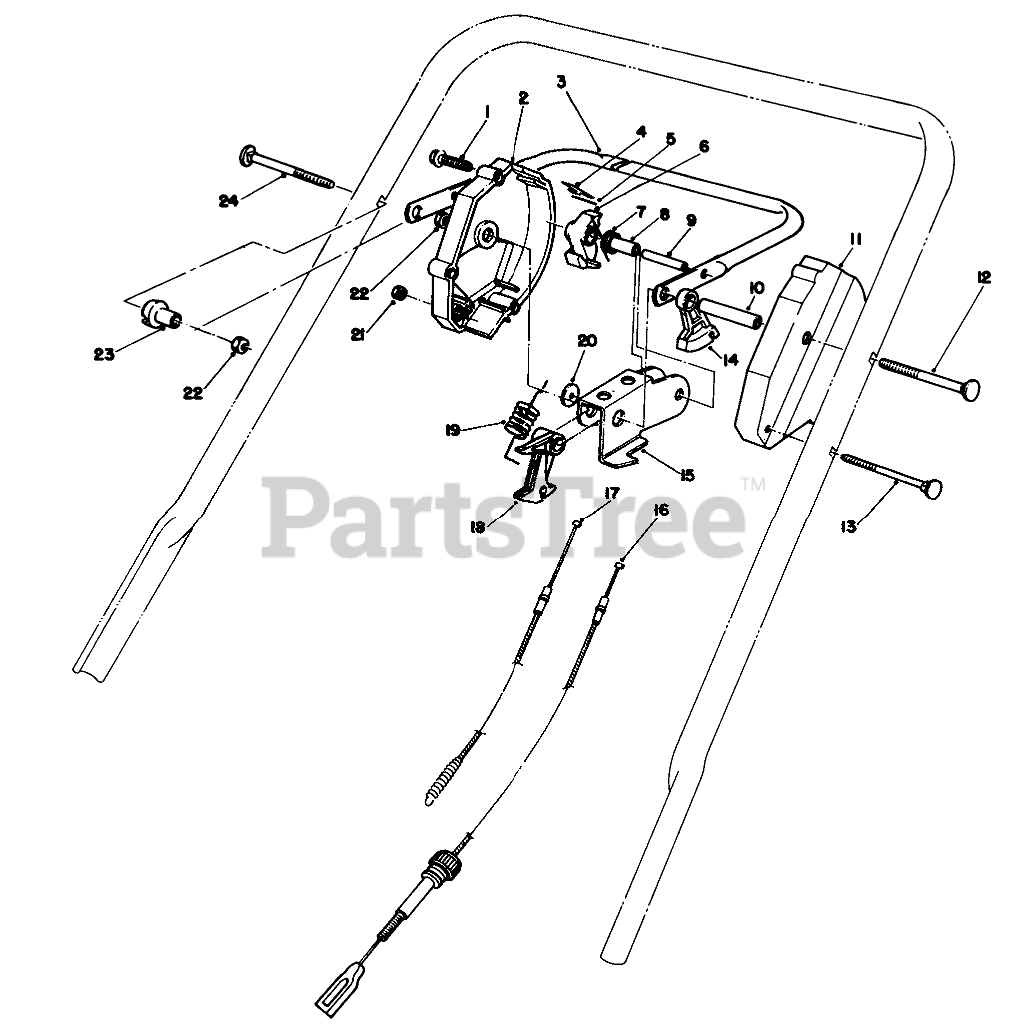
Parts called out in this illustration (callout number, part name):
1	SCREW-HWHTF
2	Housing-Control R.H. (Incl. Ref. #4 & 5)
3	Bar-Control
4	SPRING-LEAF
5	PIN-INSERT
6	HOOK-CONTROL
7	SPRING-TORSION
8	SPACER
9	PIN-ROLL, SLOTTED
10	TUBING-SPACER
11	HOUSING-CONTROL, LH
12	5/16-18 X 3 HNDLE SCREW
13	HANDLE SCREW
14	LEVER-TRACTION
15	ROCKER
16	TRACTION CABLE
17	Cable-Clutch
18	LEVER-CABLE
19	Spring-Detent
20	PLASTIC WASHER
21	NUT-HEX
22	NUT-LOCK, NI
23	SPACER-SUPPORT
24	5/16-18 X 2 HNDLE SCREW
